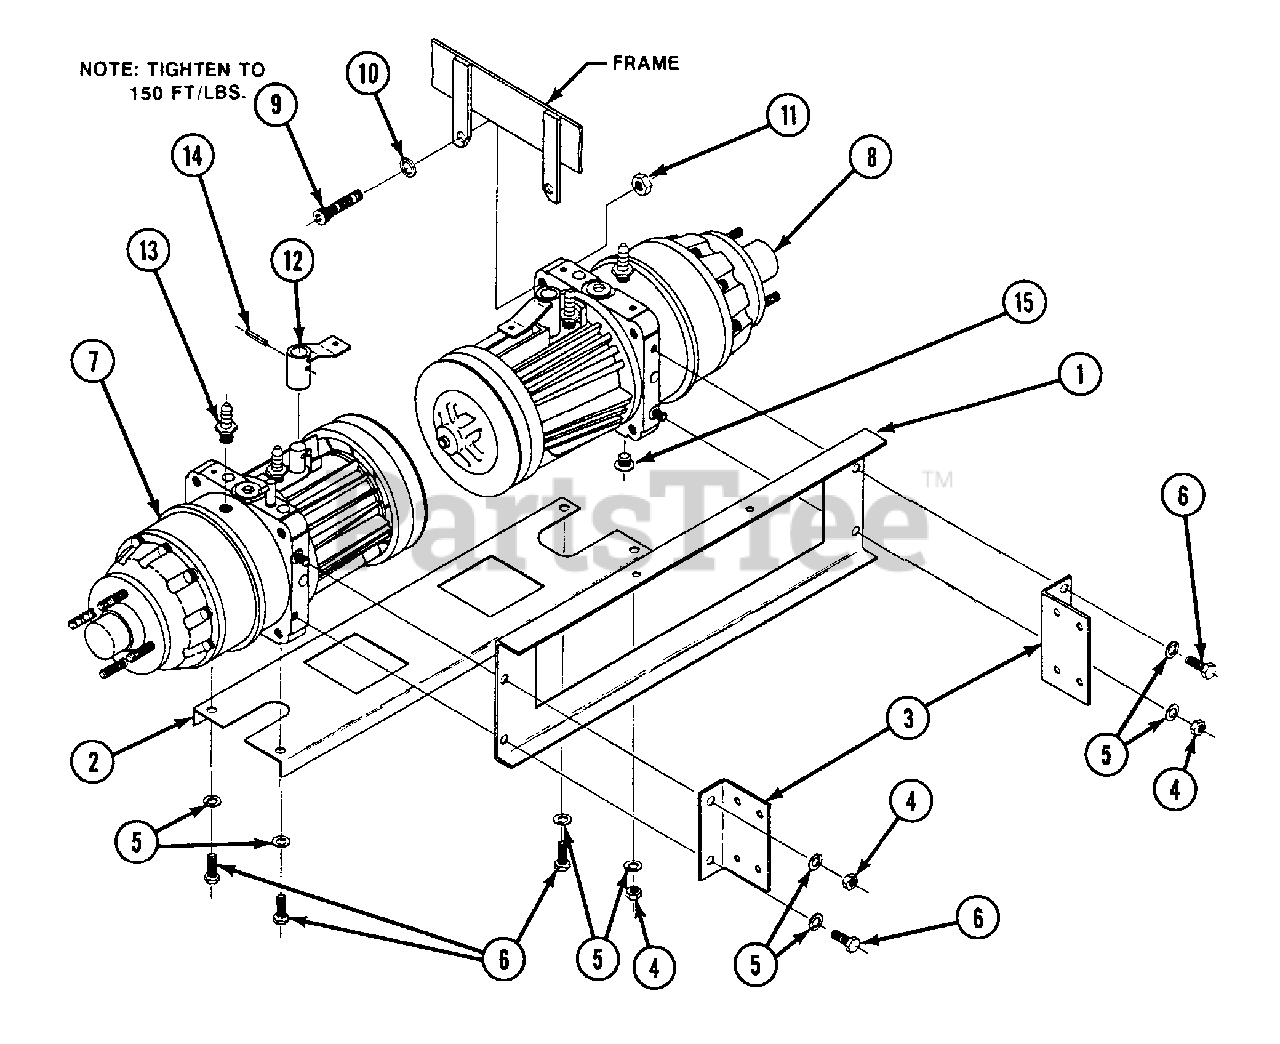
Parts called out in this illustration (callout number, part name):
1	FRONT CROSS MEMBER
2	BOTTOM CROSS MEMBER
3	DRAG BAR MOUNT
4	NUT, HEX: 1/2-13
5	LOCKWASHER, SPLT SPRNG: 1/2
6	CAPSCREW, HEX HEAD: 1/2-13 X 1-1/4
7	UNISTAT ASSEMBLY, RH
8	UNISTAT ASSEMBLY, LH
9	CAPSCREW,SKT HEAD: 5/8-11 X 2-1/4
10	LOCKWASHER, SPLT SPRNG: 5/8
11	NUT, HEX JAM: 5/8-11
12	SHIFT LEVER WELDMENT, RH (SHOWN REMOVED)
13	HOSE BARB, UNISTAT
14	ROLL PIN: 5/16 X 1-1/4
15	PLUG, 3/4-16 W/ 0-RING
